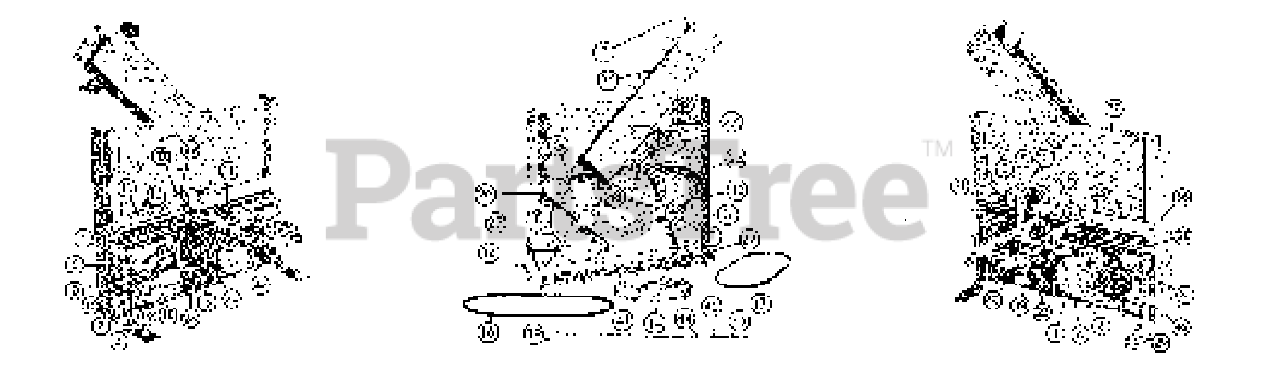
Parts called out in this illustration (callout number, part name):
2	DEFLECTOR, Second
3	STUD, Rotor
4	ADJUSTING STRAP, Idler
5	NUT, Stud
6	STRAP, Idler
7	STUD, Idler
8	COVER, Case
9	STUD, Idler
10	SPROCKET, Idler
11	SPROCKET, Rotor
12	CLIP, Rod
13	SPACER, Hitch
14	PULLEY, Tractor
16	BELT, Tractor
17	BELT, Plow
19	CHAIN, Connecting Link
21	ARM ASSEMBLY, Idler
22	SHAFT, Rotor
23	STRAP, Brace
24	PINION SHAFT, Bevel
25	GUARD, L.H.
26	GUARD, R.H.
28	CASE ASSEMBLY, Gear
30	PLATE, Back
31	SUPPORT BAR, Drive
32	CASE ASSEMBLY
33	ROTOR ASSEMBLY, L.H.
34	ROTOR ASSEMBLY, R.H.
35	DEFLECTOR ASSEMBLY
36	BAR ASSEMBLY, Side
37	PULLEY, Idler
38	SIDE PLATE, Hitch
39	CLIP, Spring
40	T-NUT, Complete
41	IDLER ROD, Lower
42	SOCKET ASSEMBLY, Rod
43	CLAMP, Hitch
44	COLLAR, Set, Idler Rod
45	SPRING, For Idler Rod
46	COLLAR, Set, 3/4"
A	PINION, Bevel
B	KEY, Sheave
C	BUSHING, For Rotor Stud
D	BUSHING, For Idler Sprocket
E	INNER BEARING RACE
F	IDLER PULLEY THRUST WASHER
G	BUSHING, For Rotor Shaft
H	BUSHING, For Bevel Pinion Shaft
I	BEARING, Idler Pulley
J	GEAR, Bevel
